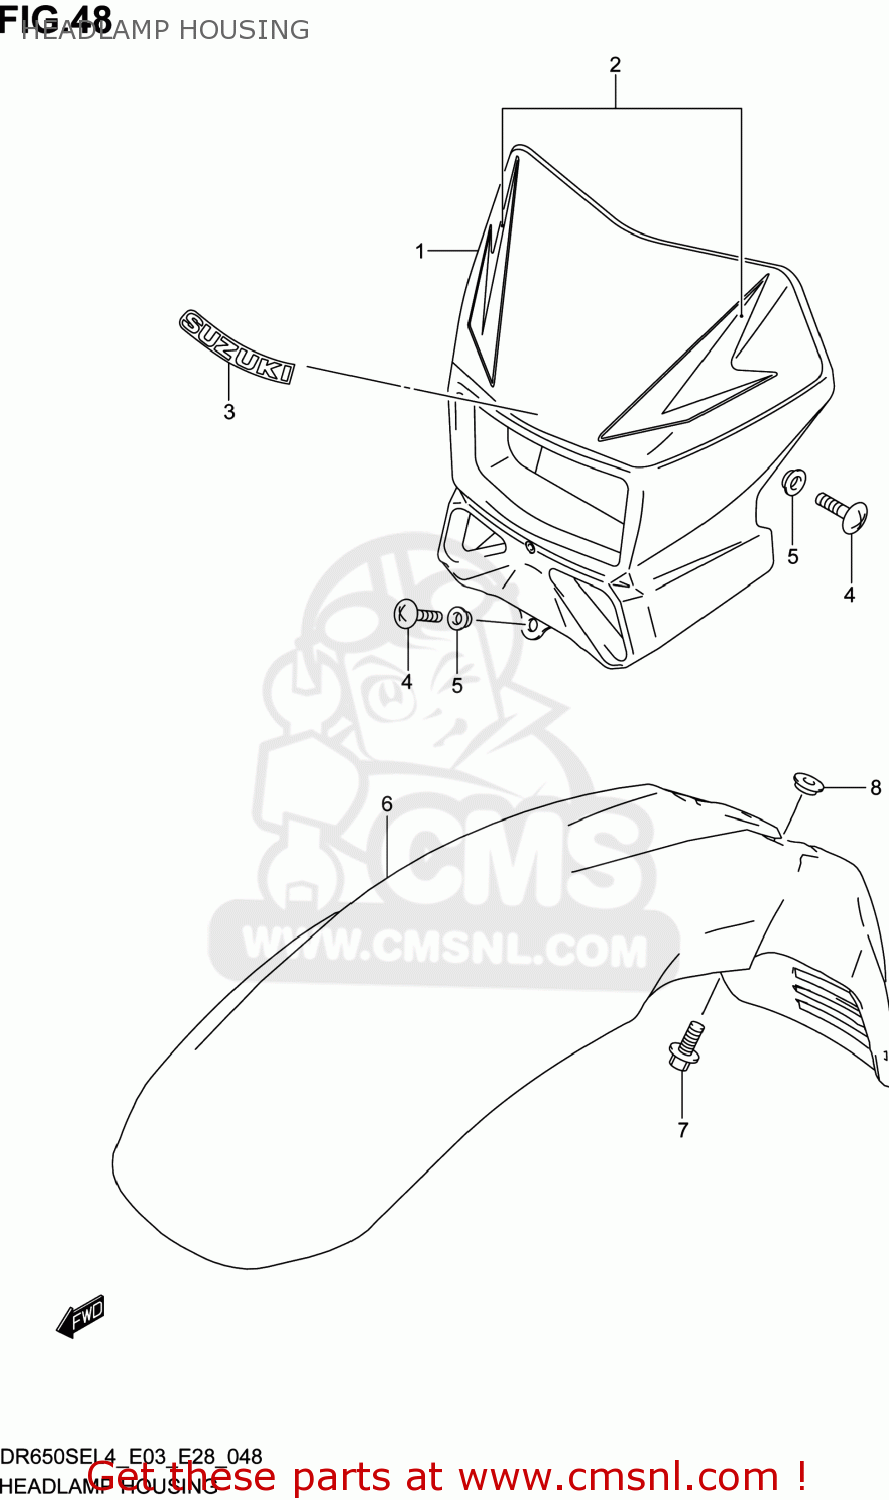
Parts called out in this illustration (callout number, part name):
1	COVER,HEADLAMP
2	TAPE SET,HEADLAMP HOUSING
3	EMBLEM,SUZUKI
4	SCREW
5	WASHER
6	FENDER,FR
7	BOLT(6X16)
8	WASHER
